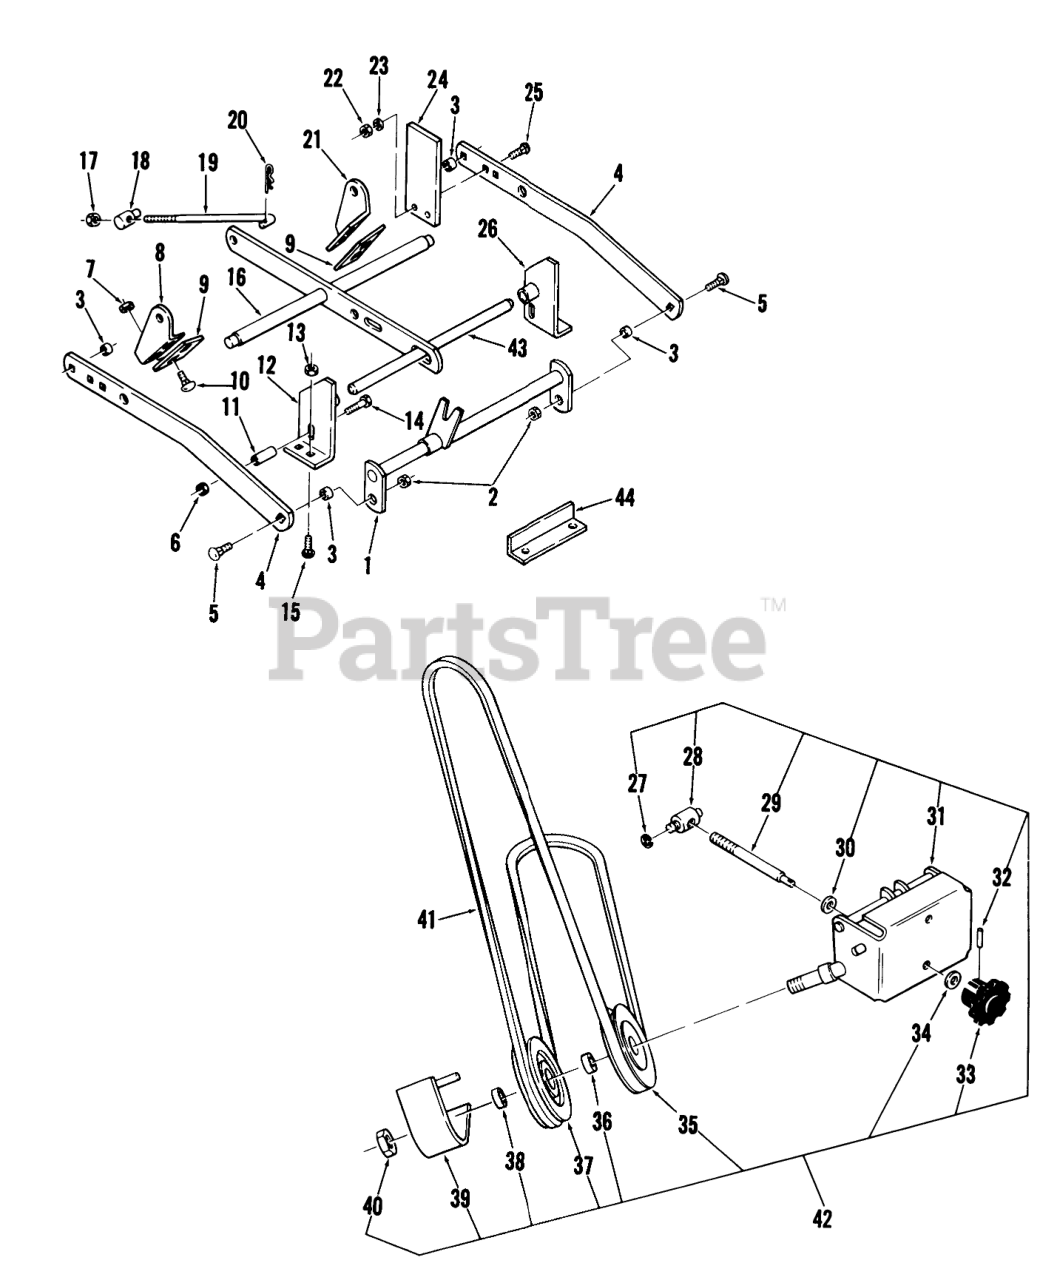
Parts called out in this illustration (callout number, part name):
1	Hitch
2	LOCKNUT-FLANGE
3	SPACER
4	Bar Draft
5	Bolt
6	Nut
7	Nut
8	Bracket-R.H.
8	Bracket-Rt. Rear
9	PLATE
10	Bolt
11	SPACER-BEARING
12	Bracket-R.H.
13	Nut
14	CARRIAGE BOLT -4
15	Bolt-Carriage
16	Leveler Ass-y.
17	NUT
18	TRUNNION-LIFT
19	ROD-LEVELER
19	ROD-LIFT
20	Hairpin
21	Bracket-L.H.
21	Bracket-L.H. Rear
22	Nut
23	Collar
24	BUMPER
25	Bolt-Carriage
26	Bracket-L.H.
27	RING-RETAINING
28	TRUNNION-DOUBLE
29	ROD ADJ
30	Washer
31	Front Support
32	PIN-ROLL
33	KNOB-ADJUSTMENT
34	Spring Washer
35	Pulley-V
36	SPACER
37	PULLEY-FLAT IDLER
38	SPACER-OUTER
39	Belt Cover
40	Nut 3/4-16 MF
41	V-BELT
42	ASM-SUPPORT,IDLER
43	Front Shaft
44	ANGLE
